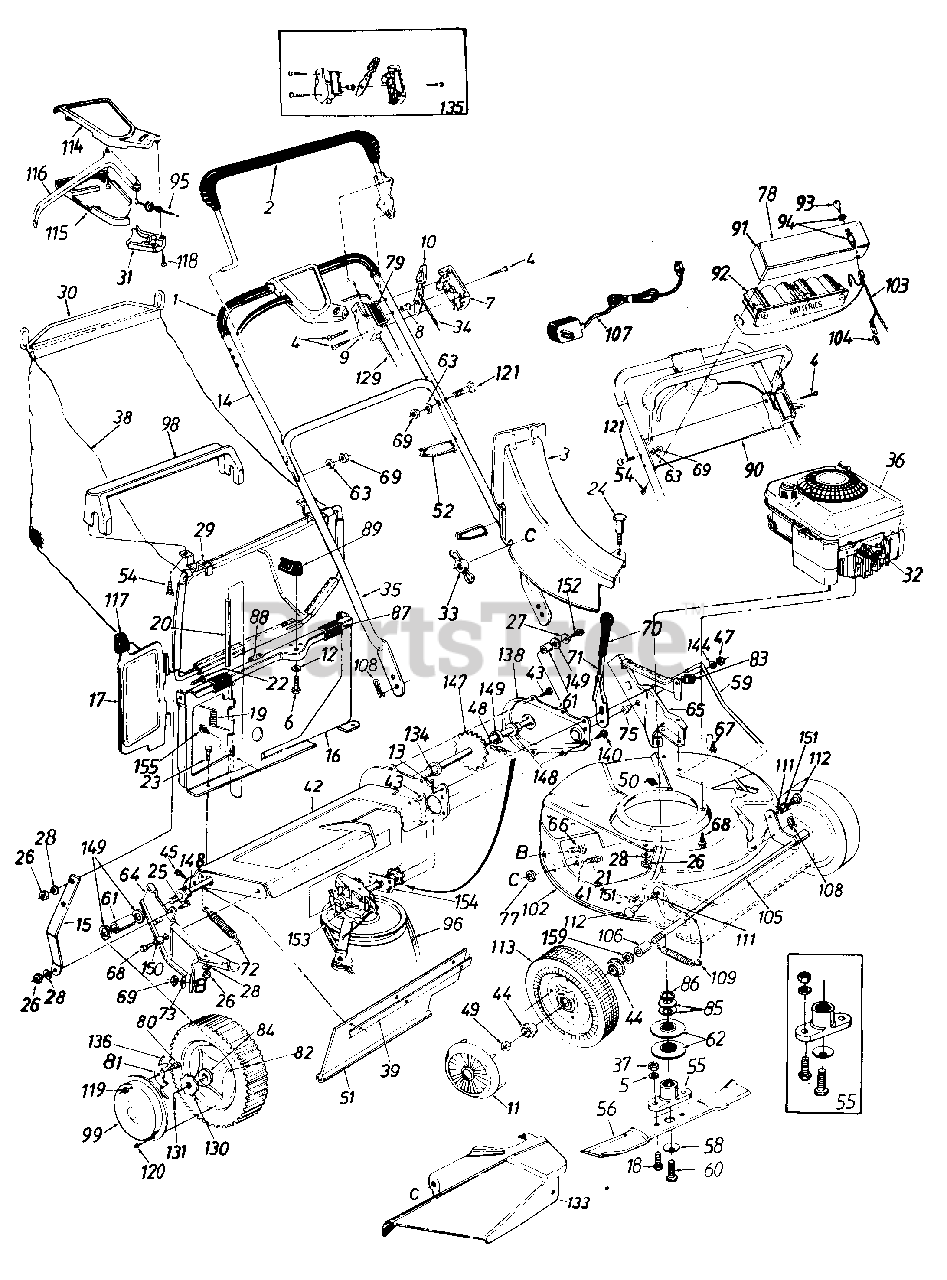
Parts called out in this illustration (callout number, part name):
1	Foam Grip
2	Control Handle Ass'y.-L.H.
3	Top Discharge Chute Ass'y.
4	Truss Mach. Scr. #12 x 1.50" Lg.
5	L-Wash. 3/8" I.D.*
6	Hex Wash. TT-Tap Scr. 1/4-20 x .75" Lg.
7	Control Panel Half
8	Control Disc Pin
9	Clutch Panel Half
10	Throttle Control Lever
11	Hub Cap
12	Spring Wash. .32" I.D.
13	Cotter Pin 3/32" Dia. x .75"*
14	Upper Handle
15	Panel Support Brkt.
16	Top Catcher Panel Ass'y.
17	Top Discharge Door
18	Hex Bolt 3/8-24 x 1" Lg.
19	Torsion Spring
20	Pivot Pin
21	Carriage Bolt 1/4-20 x .62
22	Truss Mach. Scr. 1/4-20 x 3/4" Lg
23	Hex Bolt 1/4-20 x .50" Lg.
24	Shoulder Bolt .312 Dia. x .18 Lg.-Special
25	Hex Bolt 1/4-20 x .62" Lg.
26	Hex Nut 1/4-20 Thd.
27	Bell-Wash. 1/4" I.D.
28	L-Wash. 1/4" I.D.*
29	Front Grass Catcher Frame
30	Grass Catcher Handle
31	Cable Mtg. Cap
32	Spark Plug Insulator
33	Wing Nut w/Washer
34	Throttle Control Wire 58"
35	Lower Handle
36	Engine
37	Hex Nut 3/8-24 Thd.
38	21" Top Discharge Grass Bag-Black
39	Retainlng Strip
41	Fl-Wash. .344" I.D. x .62"
44	Flange Ball Bearing 1/2" I.D.
45	Hex AB-Tap Scr. 1/4 x .62"
47	Hex Patch L-Nut 3/8-24 Thd.
48	#48 Chain .500" Pitch x 30 Links
49	Hex L-Nut 1/2-20 Thd.
51	Rear Flap 3.75" x 17.30" Lg.
52	Cable Tie
54	Hex AB-Tap Scr. 1.0" Lg .
55	Blade Adapter Kit
56	21" Blade
58	Bell-Wash. .46" I.D.
59	Height Adj. Rod 19.42" Lg.
60	Hex Bolt 7/16-20 x 1.5" Lg. (Grade 5)
61	Spacer .513" I.D. x .703" O.D. x .69" Lg.
62	Serrated Pulley Half
63	L-Wash. 5116" I.D.*
64	R.H. Handle Wheel Brkt. Ass'y.
65	L.H. Handle Wheel Brkt. Ass'y.
66	Carriage Bolt 5/16-18 x .62"*
67	Hex Wash. Hd. B-Tap Scr. 5/1 6-18
68	Hex Wash. Hd. TT-Tap Scr. 3/8-16
69	Hex Nut 5/16-18 Thd.
71	Height Adj. Lever
72	Extension Spring .50" O.D. x 3.80" Lg.
73	Bell-Wash. 5116" I.D.
75	Shld. Spacer. 500" Dia.
77	Bolt Retainer 1/4 x .50" O.D.
78	Instruction Label
79	Control Label
80	Shld. Scr. .342" Dia. x .268
81	Pawl
82	Wheel Ass'y. Comp.
83	Clamp
84	Bearing 1/2" I . D.
85	Wave Washer 1.005" I.D.
86	Serrated Washer 1.0" I.D.
87	Panel Clip
88	Foam Strip 1" Lg.
89	Grass Catcher Locking Knob
90	Lower Battery Tray
91	Upper Battery Tray
92	12 Volt Battery
93	Key
94	Key Switch
95	S.P. Cable
96	"V"-Belt
98	Bag Handle (Black)
99	Rear Hub Cap
104	Plug
105	Front Axle Ass'y.
106	Sleeve .526" I.D. x .690" O.D. x .880" Lg.
107	Battery Charger
108	Intern. Cotter Pin 5/16" Dia.
109	Extension Spring .50" O.D. x 3.20" Lg.
111	Intern. L-Wash. 3/8 I.D.*
112	Shld. Bolt .575" Dia. x .42
112	"T" Tread (7 x 1.75")
113	Wheel Ass'y. Comp.
114	Self-Propelled Control Cover
115	Self-Propelled Control Cover
116	Control Lever
117	Door Grip
118	Fl-"C"-Sunk Hd. Tap Scr. #10 x .75" Lg.
119	Hex Ins. L-Nut 1/4-20 Thd.
120	Pan Hd. Tap Scr. #12 x .5" Lg.
121	Curved Carr. Bolt 5/16-18 x 1.38" Lg
129	Control Cable 46" Lg.
130	Ratchet Wheel 1.62" O.D.
131	Cotter Pin 118" Dia. x 1.00" Lg.*
133	Side Chute Deflector Ass'y.
134	Hex Flange Bearing
135	Kit-Control Housing Comp.
136	Spring-Nylon
144	Fl-Wash. .385" I.D. x .87"
147	Rear Shaft Ass'y. 21.94" Lg.
148	Hex Flange Bearing .506" I.D. Plastic
149	Fl-Wash. .531" I.D. x .930"
150	Spacer .383" I.D. x .503 O.D.
151	Flanged Nyliner Brg.
152	Hex Bolt 1/4-20 x .62" Lg. (Grade 5)
153	Transmission Comp.
154	Hex Bearing Cup
155	Hex B-Tap Scr. #10 x .38
159	Fl-Wash. .51" I.D. x .75" O.D.
17055B-0637	AXLE ASSY-CHAIN - POWDER BLACK (0637)
17055B-0638	AXLE ASSY-CHAIN - MTD/TROY-BILT RED (0638)
17055B-0665	AXLE ASSY-CHAIN - YARDMAN GREEN (0665)
